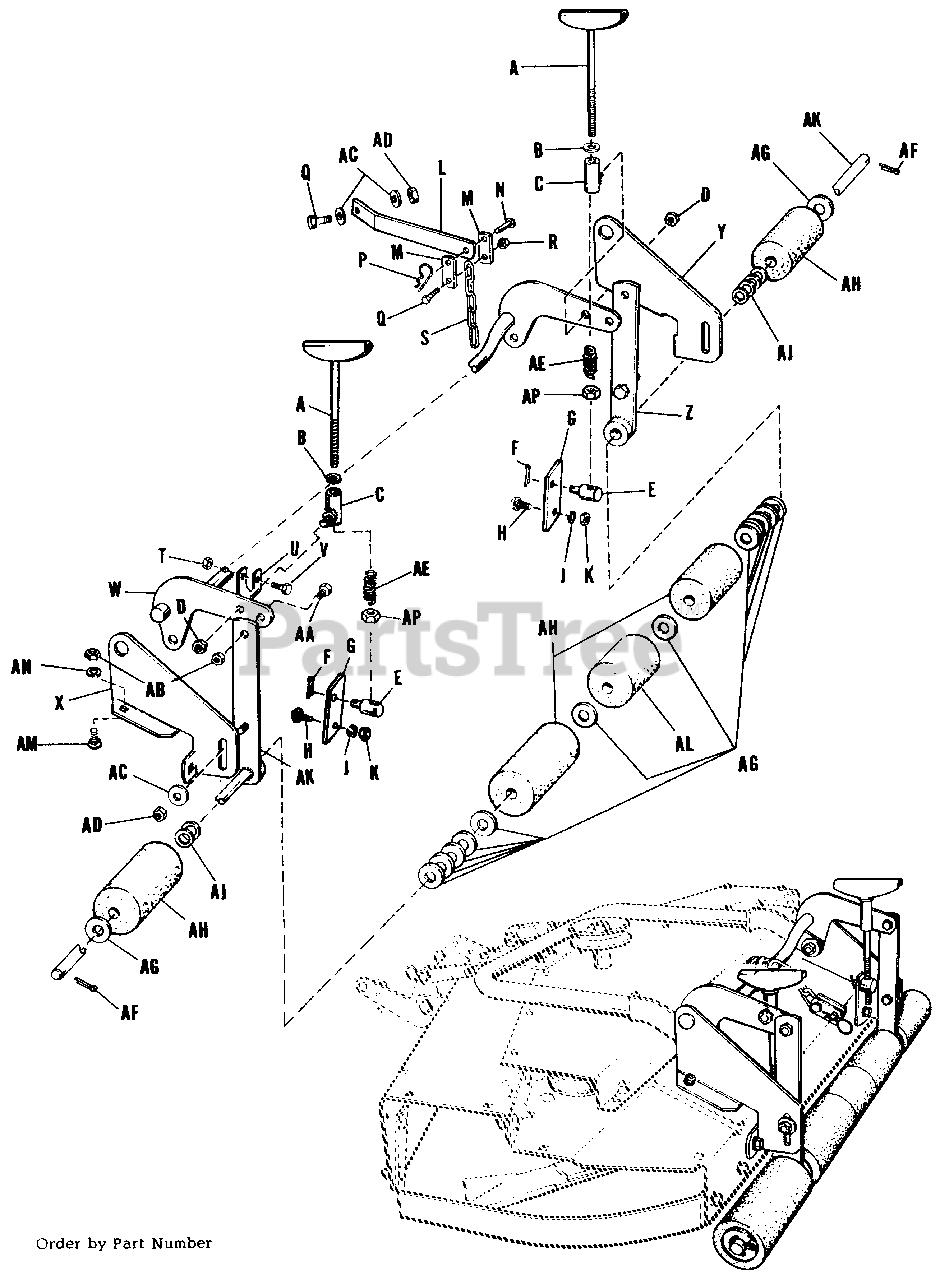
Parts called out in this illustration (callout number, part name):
A	Screw Assembly, Adjusting
B	Washer, Plain, 3/8"
C	Socket Assembly, Crank
D	Nut, Hex, Full, Lock, 3/8"-16 NC
F	Cotter Pin, 3/32" x 3/4" lg.
G	Link, Lift
H	Bolt, Carriage, 3/8"-16 NC x 3/4" lg.
J	Washer, Lock, 3/8"
K	Nut, Hex, Full. 3/8"-16 NC
L	Lever, Mower Lift
M	Link, Mower Lift
P	Clip, Spring
Q	Capscrew, Hex Hd., 3/8"-16 NC x 1" lg.
R	Nut, Hex, Full, Lock, 3/8"-16 NC
S	Chain
T	Nut, Hex, Full, Lock, 3/8"-16 NC
U	Clip, Chain
V	Capscrew, Hex Hd., 3/8"-16 NC x 1-1/2" lg.
W	Arm Assembly, Rocker
X	Bracket, Roller, L.H.
Y	Bracket, Roller, R.H.
Z	Bar Assembly, Roller
AA	Capscrew, Hex Hd., 3/8"-16 NC x 1" lg.
AB	Nut, Hex, Full, 3/8"-16 NC
AC	Washer, Plain, 3/8"
AD	Nut, Hex, Full, Lock, 3/8"-16 NC
AE	Spring, Adj. Screw
AF	Pin, Cotter, 3/16" x 1" lg.
AK	Shaft & Support Arm.
AM	Bolt, Carriage, 3/8"-16 NC x 3/4" lg.
AN	Washer, Lock, 3/8"
AP	Nut, Hex. Full.
